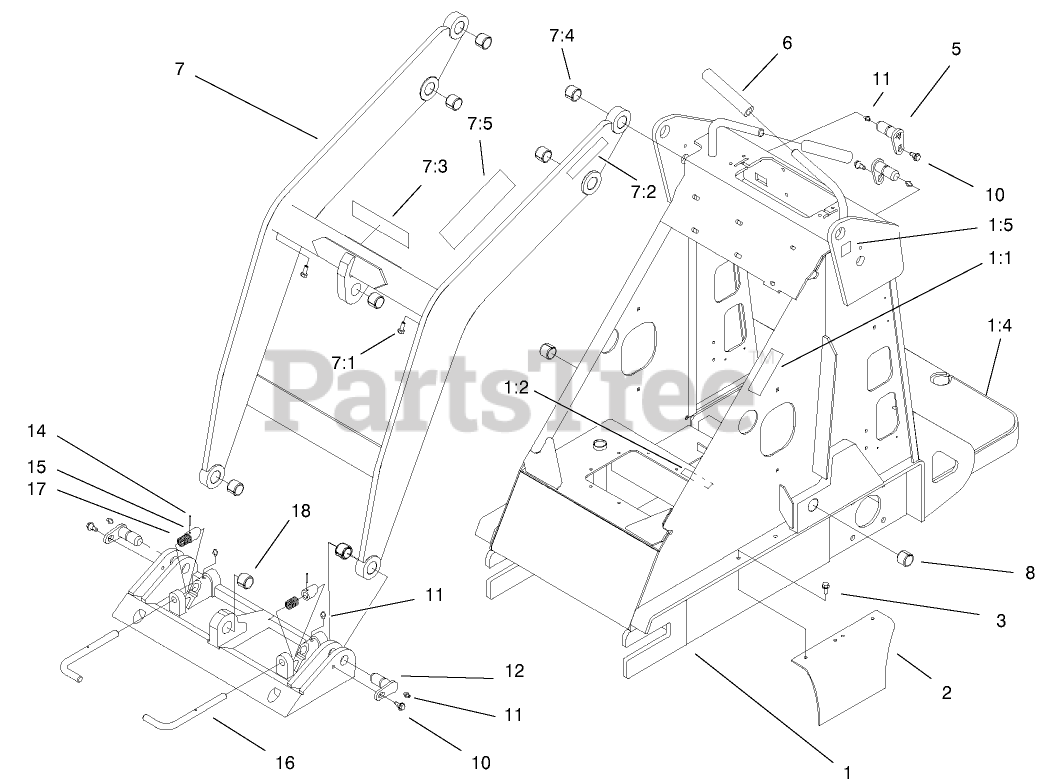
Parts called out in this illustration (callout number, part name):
1	FRAME ASM
1:1	DECAL-WARNING
1:2	DECAL-WARNING
1:4	TREAD-FOOT
1:5	DECAL-POINT, LIFT
2	Cover-Chain
3	SCREW-HWHTF
5	PIN-PIVOT
6	GRIP-CUSHION
7	Loader ASM
7:1	SCREW-HWHTF
7:2	DECAL-WARNING, KEEP HANDS AWAY
7:3	DECAL-CAUTION
7:4	BUSHING-TENSION
7:5	DECAL-DANGER
8	BUSHING-TENSION
10	BOLT-SHOULDER
11	FITTING-GREASE
12	PIN-PIVOT
14	PIN-SPECIAL
15	CAM-ATTACH, QUICK
17	SPRING-COMPRESSION
18	BUSHING-TENSION
